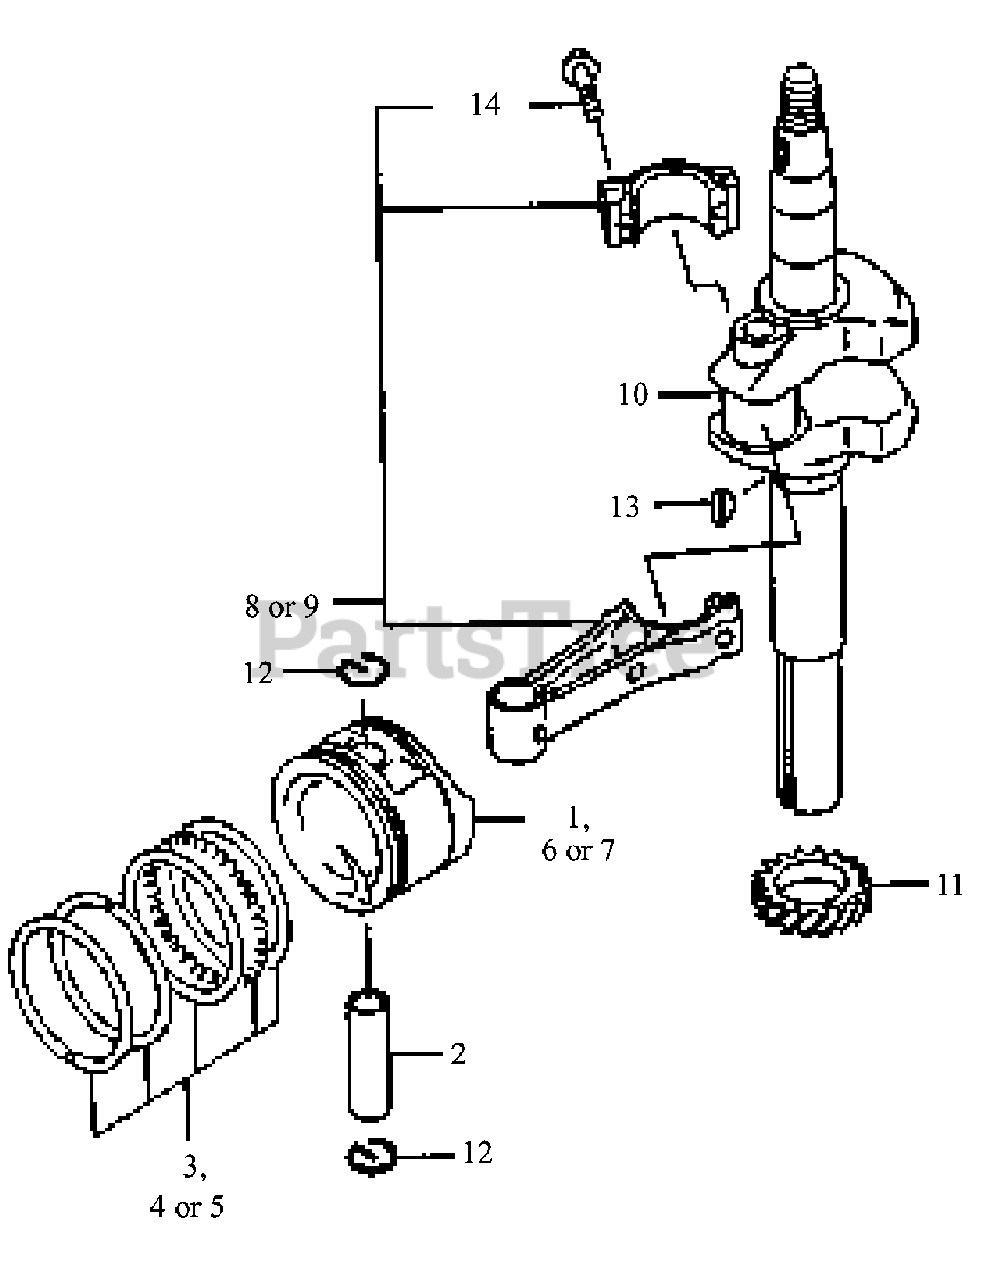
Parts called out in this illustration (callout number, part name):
1	Piston, Engine
3	Ring, Set Piston
4	Ring, Set Piston. 0.25
5	Ring, Set Piston, 0.50
6	Piston, Engine 0.25
7	Piston, Engine 0.50
8	Rod, Connecting
9	Rod, Connecting us0.50
10	Crankshaft
11	Gear, Helical
14	Bolt, Connecting Rod
